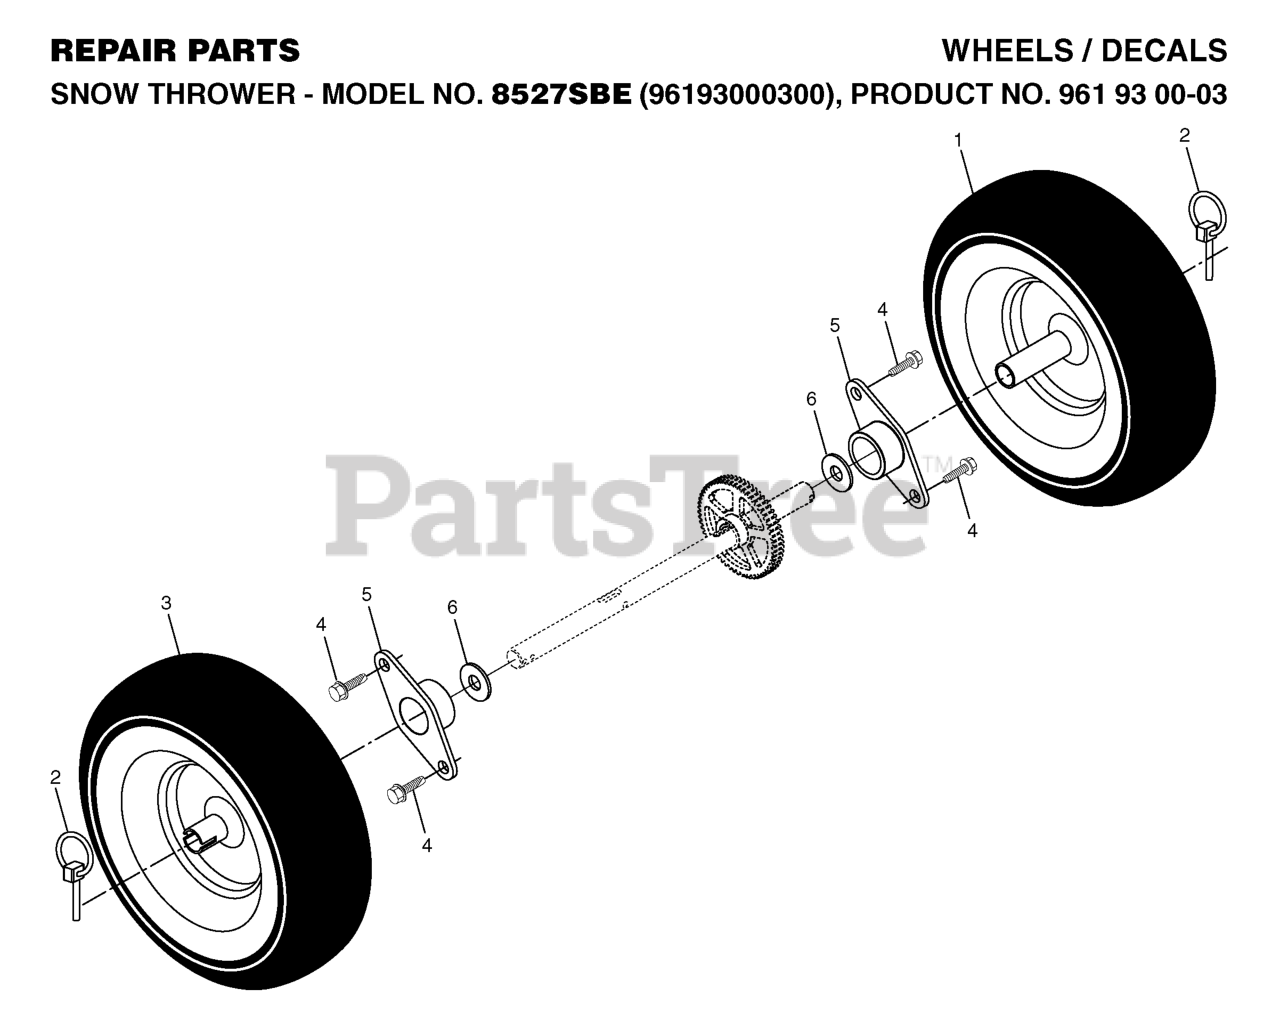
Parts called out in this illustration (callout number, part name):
1	WHEEL.ASM.LT.16"GRY.XTRAC
2	PIN KLIK, 1/4
3	WHEEL.ASM.RT.16".GRAY.SN
5	BEARING, AXLE
6	WASHER TRUST 1"
